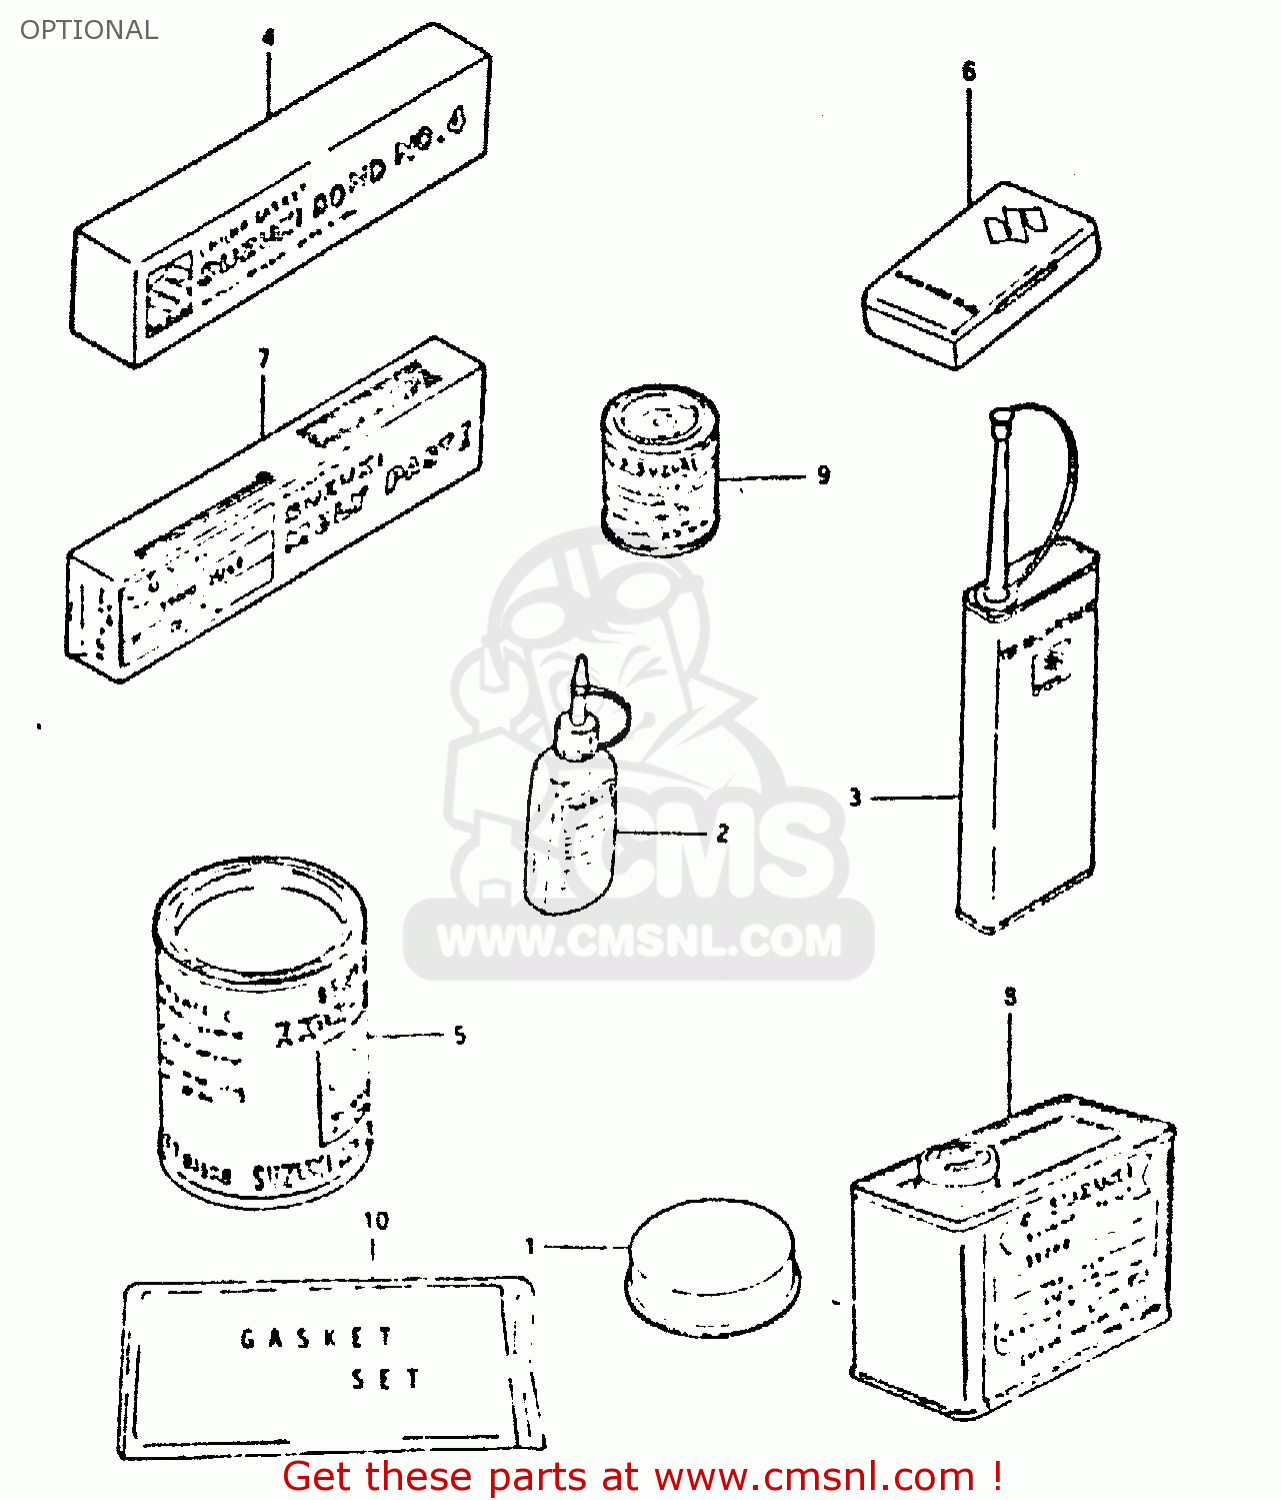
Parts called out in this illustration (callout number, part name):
1	GREASE,PBC FOR BRK PAD 20G
2	THREAD LOCK SUPER (1332B)
3	THREAD LOCK NO.1401 CLEAR 200G
4	BOND 1104
5	GREASE(C)EP2 LITHIUM 150G
6	TUBE REPARING TOOL
7	SUZUKI MOLY PASTE
8	PAINT (BLACK)
9	PAINT,BLACK
10	GASKET SET
